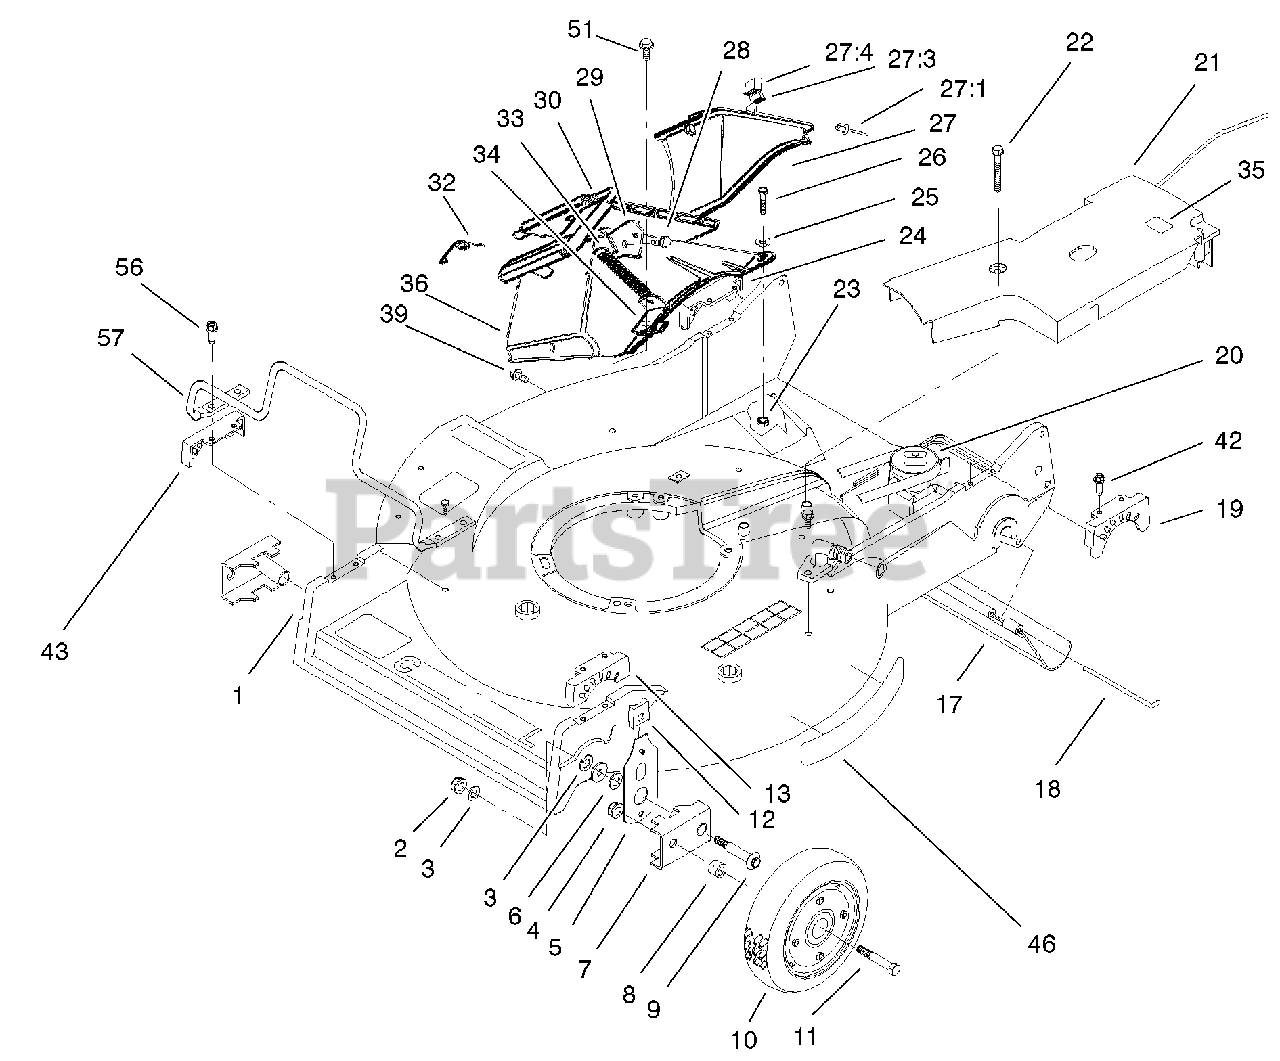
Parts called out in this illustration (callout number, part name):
1	Decal-Danger
2	Screw-Tapping
3	Grip-Lower
4	Pin-Groove
5	Trigger-HOC
6	Cap-R.H. Hinge Bolt
7	Screw-Thread Forming
8	Grip-Upper
9	Screw-Pan Hd. Phillips
10	Screw-Hex Hd. Cap
11	Cap-L.H. Hinge Bolt
12	Spring-Door
13	Door-Discharge (Incl. Ref. # 1)
15	Spacer-Door
16	Spacer-Handle
17	Spacer-Handle
18	Ramp-Discharge
19	Screw-Tapping
20	Nut-Push
21	Retainer-Shaft
22	Pivot-Front
23	Nut-Lock
25	Wheel & Tire Assembly
26	Bolt-Wheel
27	Decal-Deck 400XP
28	Housing (Incl. Ref. #27)
29	Cover-Belt
30	Screw-Hex Hd. Cap
31	Guide-Belt Rear
32	Screw-HH
